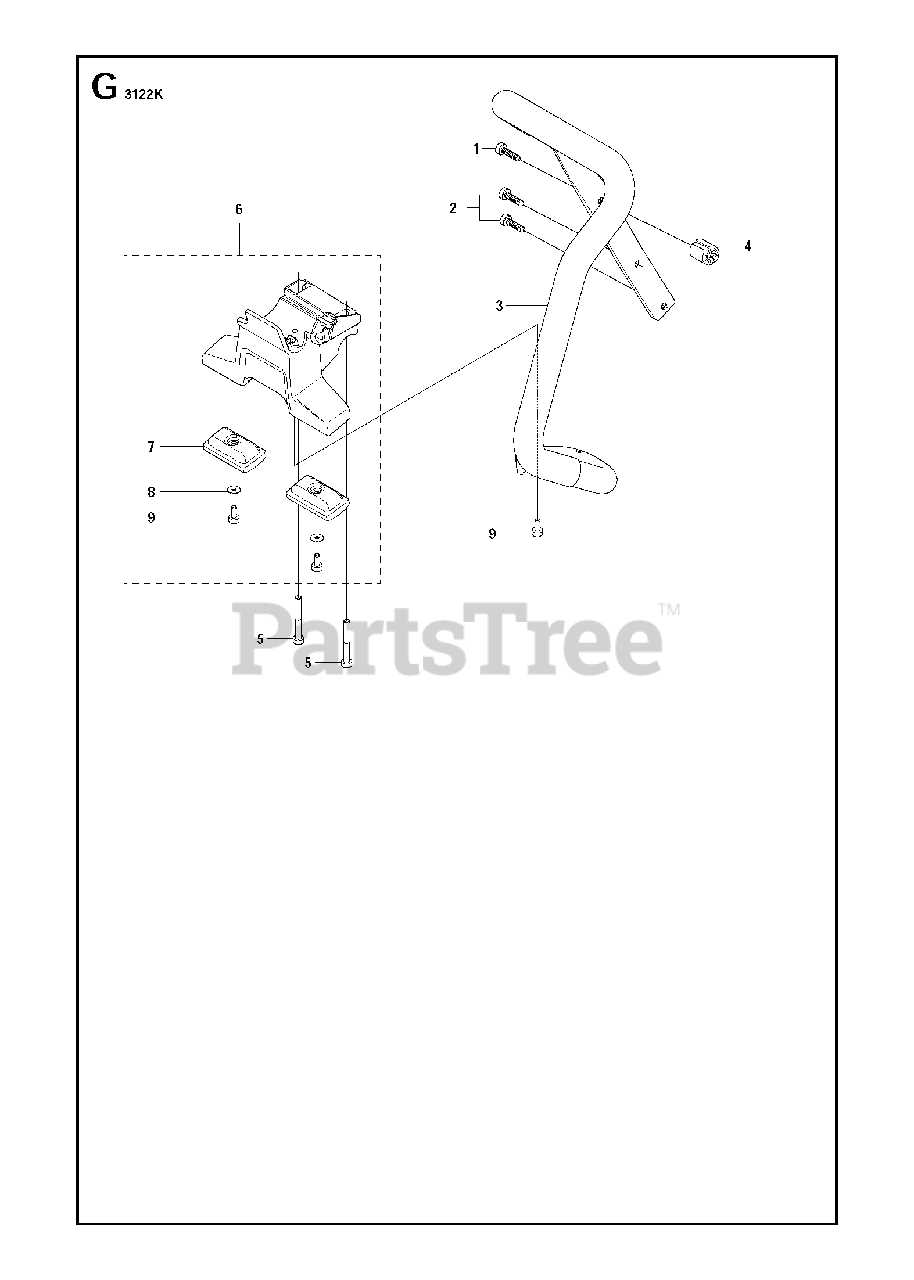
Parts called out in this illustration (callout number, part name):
1	SCREW ITXSCM
2	SCREW ITXSCT
3	HANDLE
4	ANTIVIBRATION ELEMENT
5	SCREW ITXSCM
6	GROUND SUPPORTIncl. 7 - 9
9	SCREW ITXSCM
